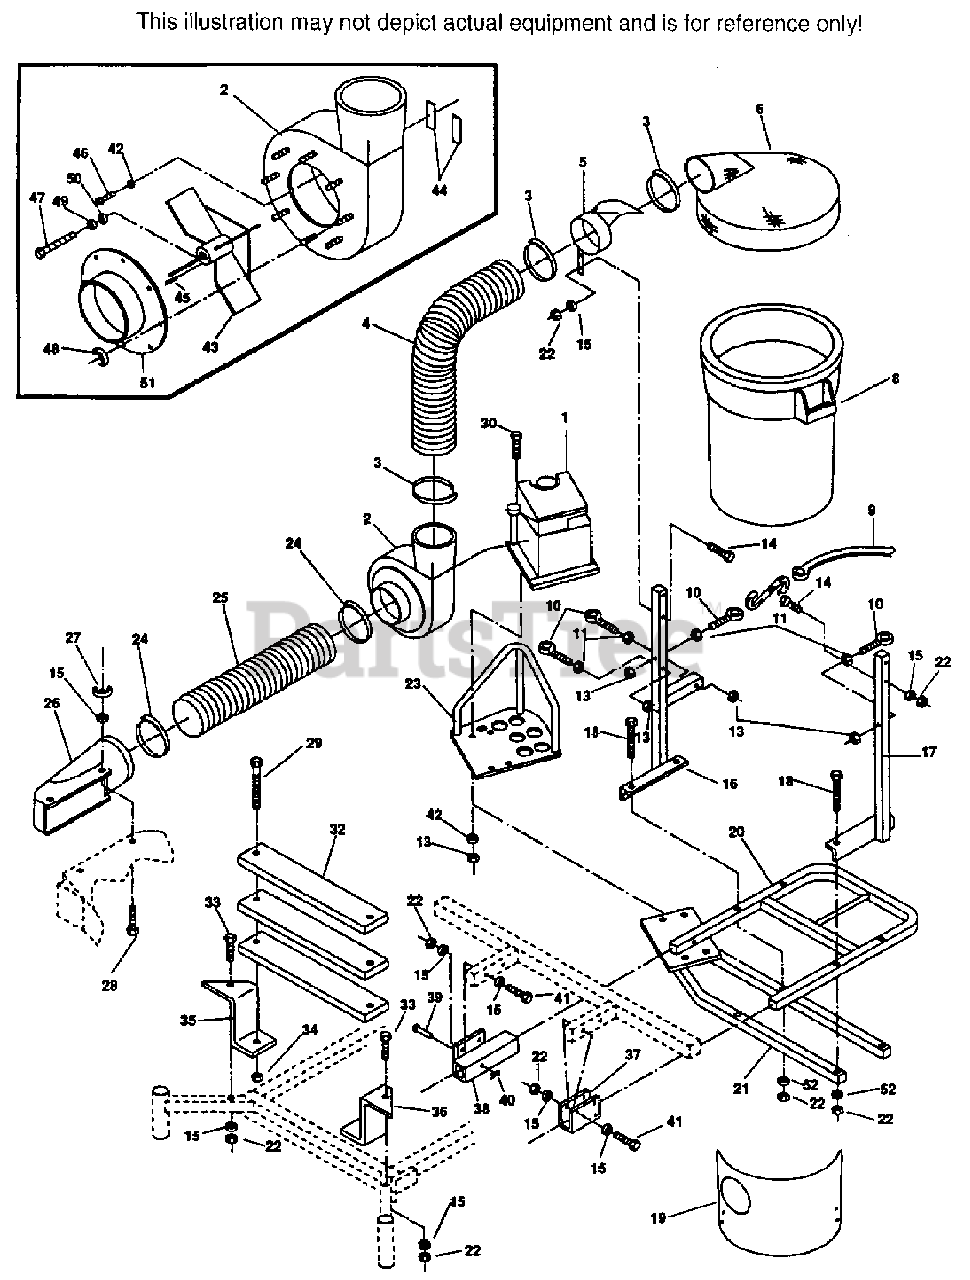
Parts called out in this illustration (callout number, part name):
1	KOHLER ENGINE 5HP
2	BLOWER HOUSING
3	HOSE CLAMP 6"
4	HOSE 6"ID X 37" LONG
5	HOSE SUPPORT ASSEMBLY
6	BUCKET COVER ASSEMBLY
8	BUCKET
9	RUBBER STRAP
10	EYEBOLT, 5/16-18 X 2-3/4"
16	R.H. UPRIGHT POST
17	L.H. UPRIGHT POST
19	DUST SHIELD
20	CATCHER, BARREL SUPPORT FRAME
21	ENGINE MOUNTING FRAME
23	ENGINE GUARD
24	HOSE CLAMP 8"
25	HOSE 8"ID X 37" LONG
26	BOOT
27	WING NUT, 3/8-16
32	WEIGHT BAR
35	WEIGHT BAR MOUNTING BRACKET, R.H.
36	WEIGHT BAR MOUNTING BRACKET, L.H.
37	CATCHER SUPPORT, L.H.
38	CATCHER SUPPORT, R.H.
39	CLEVIS PIN
40	HAIR PIN
44	SPACER
45	KEY, 1/4 X 1/4 X 1-1/2"
48	ELASTIC WING NUTS, 5/16-18
51	INLET ADAPTER
52	FLAT WASHER, 3/8 X 1-1/2 X 7 GA.
